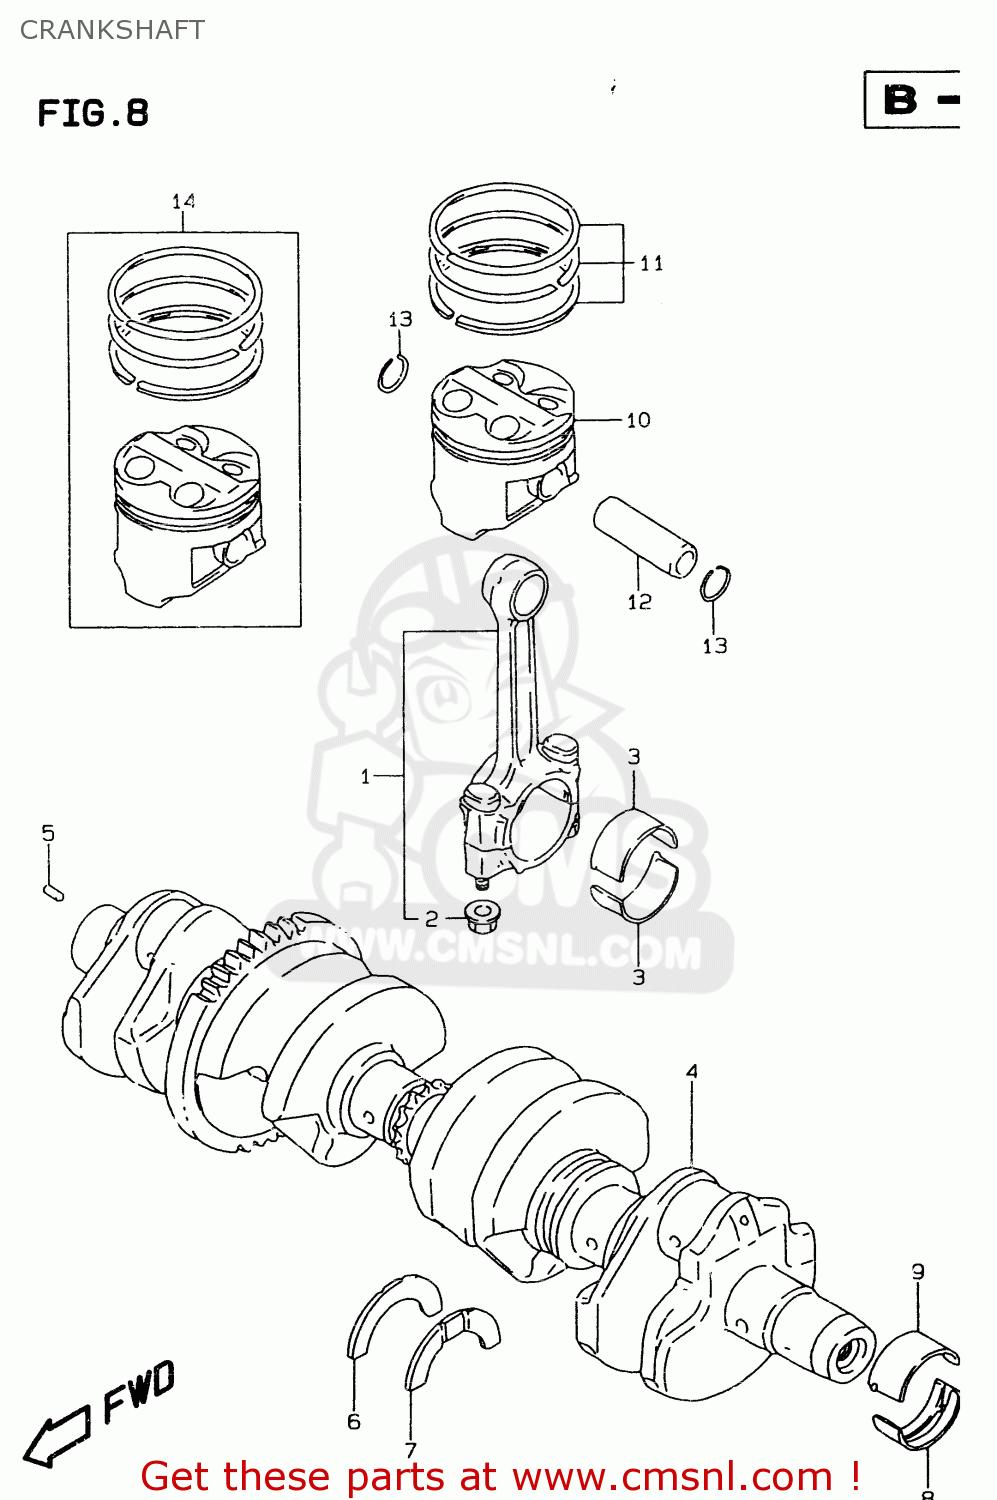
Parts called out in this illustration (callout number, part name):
1	ROD ASSEMBLY,CONNECTING
2	NUT
3	BEARING,CRANK PIN
4	CRANKSHAFT SET
5	PIN
6	PLATE,CRANK THRUST
7	PLATE,CRANK THRUST
8	BEARING,CRANKSHAFT LWR
9	BEARING,CRANKSHAFT UPR
10	PISTON
11	RING SET,PISTON
12	PIN,PISTON
13	CIRCLIP
14	PISTON SET (OS:1.0)
